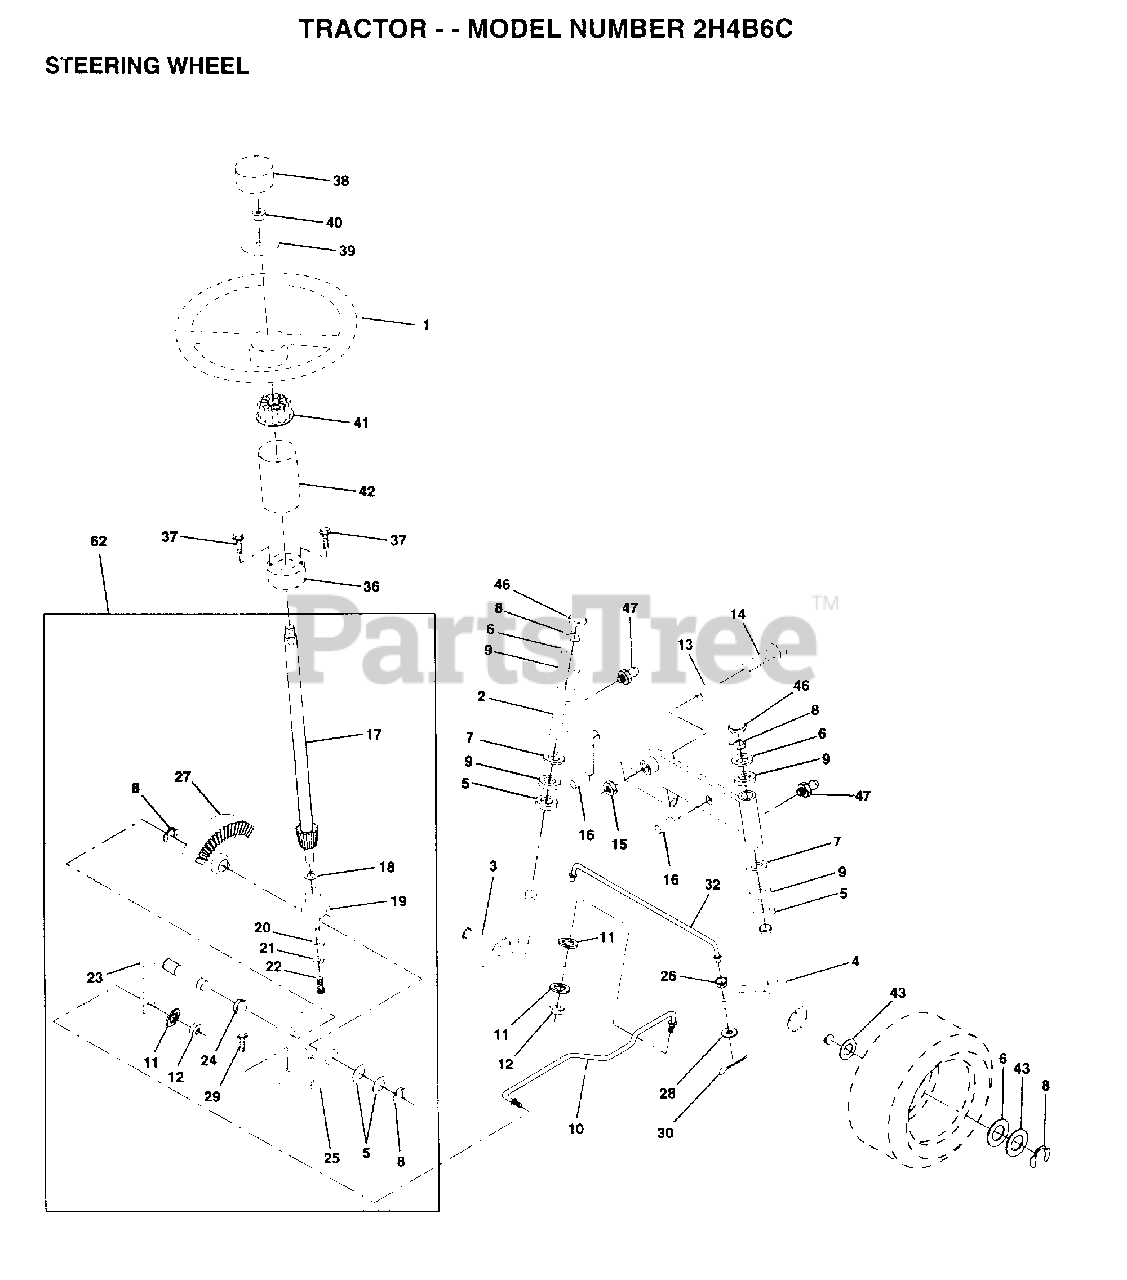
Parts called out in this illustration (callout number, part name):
2	AXLE ASM FRONT
3	SPINDLE LH
4	SPINDLE RH
5	WASHER .T
6	WASHER
7	WASHER
8	RING
9	COL. SRTG. BEAR.
11	LOCKWASHER
13	BEARING
14	BOLT HEX 5/8-11
15	"NUT-LOC,FLANGE LT"
16	AXLE PIN
17	SHAFT ASM
18	THRUST WASHER
19	SUPPORT.SHAFT
21	LOCKWASHER
22	SCREW.SCKTHD.CAP
24	NYLINER T
25	"BRKT,STEERING"
26	BUSHING.DRAGLINK
27	GEAR SECTOR
28	WASHER
29	SCREW
30	COTTER PIN
32	TIE ROD
38	ST WHL INSERT CAP
39	WASHER T
40	GRIPCO NUT
41	ADAPTER-WHEEL LT
42	"TUBE, STR SHAFT"
43	WASHER
46	CAP
47	ZERK M
